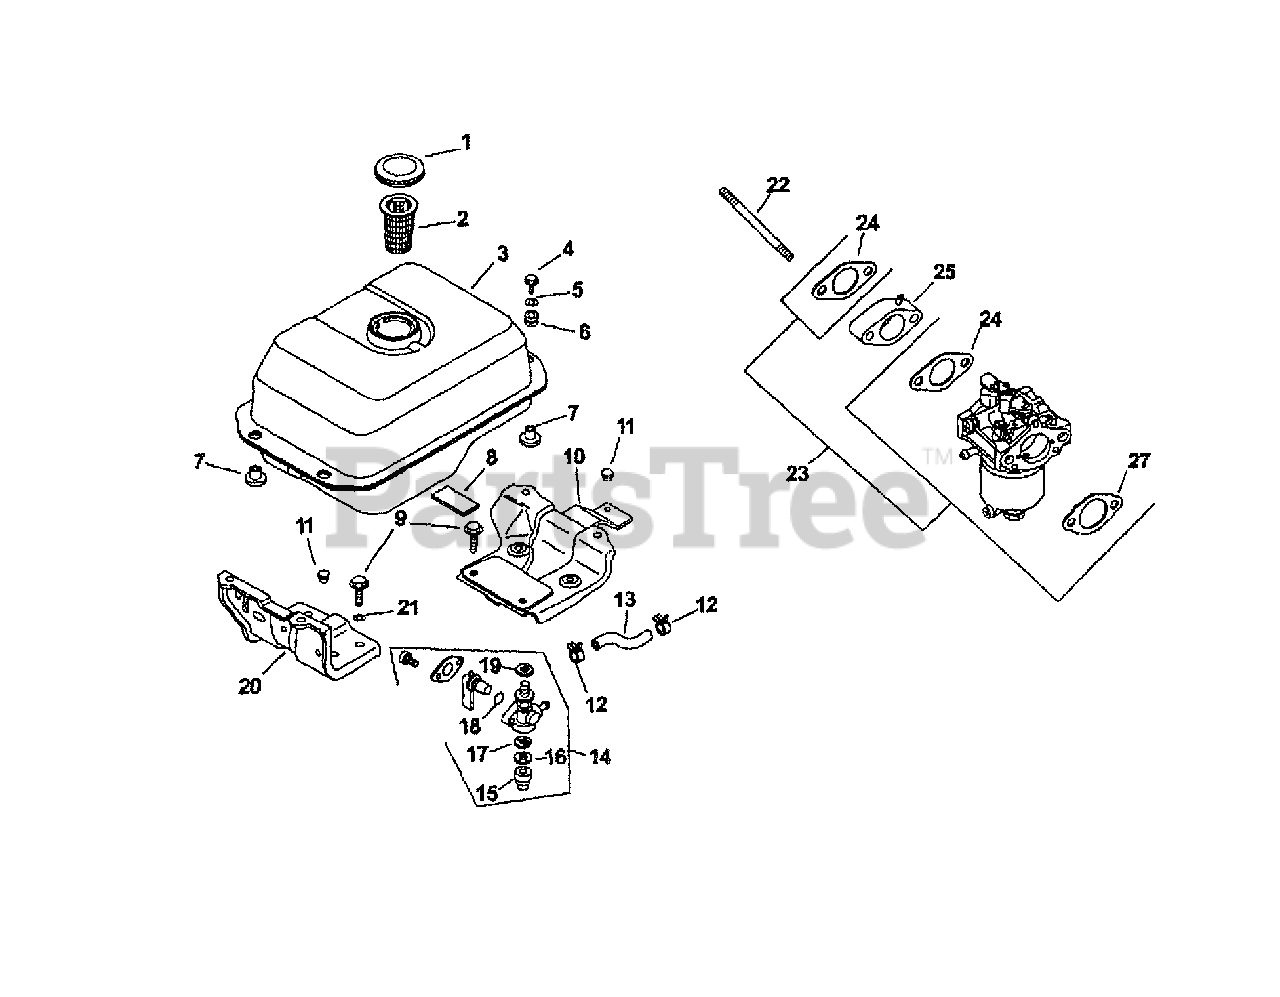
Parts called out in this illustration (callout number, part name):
1	Cap, Fuel Tank
8	Damper, Locating
10	Bracket, Fuel Tank
14	Valve, Fuel Shut Off
17	Filter, Screen
20	Bracket, Fuel Tank
22	Stud, Carburetor
23	Carburetor Kit
24	Gasket, Intake
25	Manifold, Intake
27	Gasket, Air Cleaner
